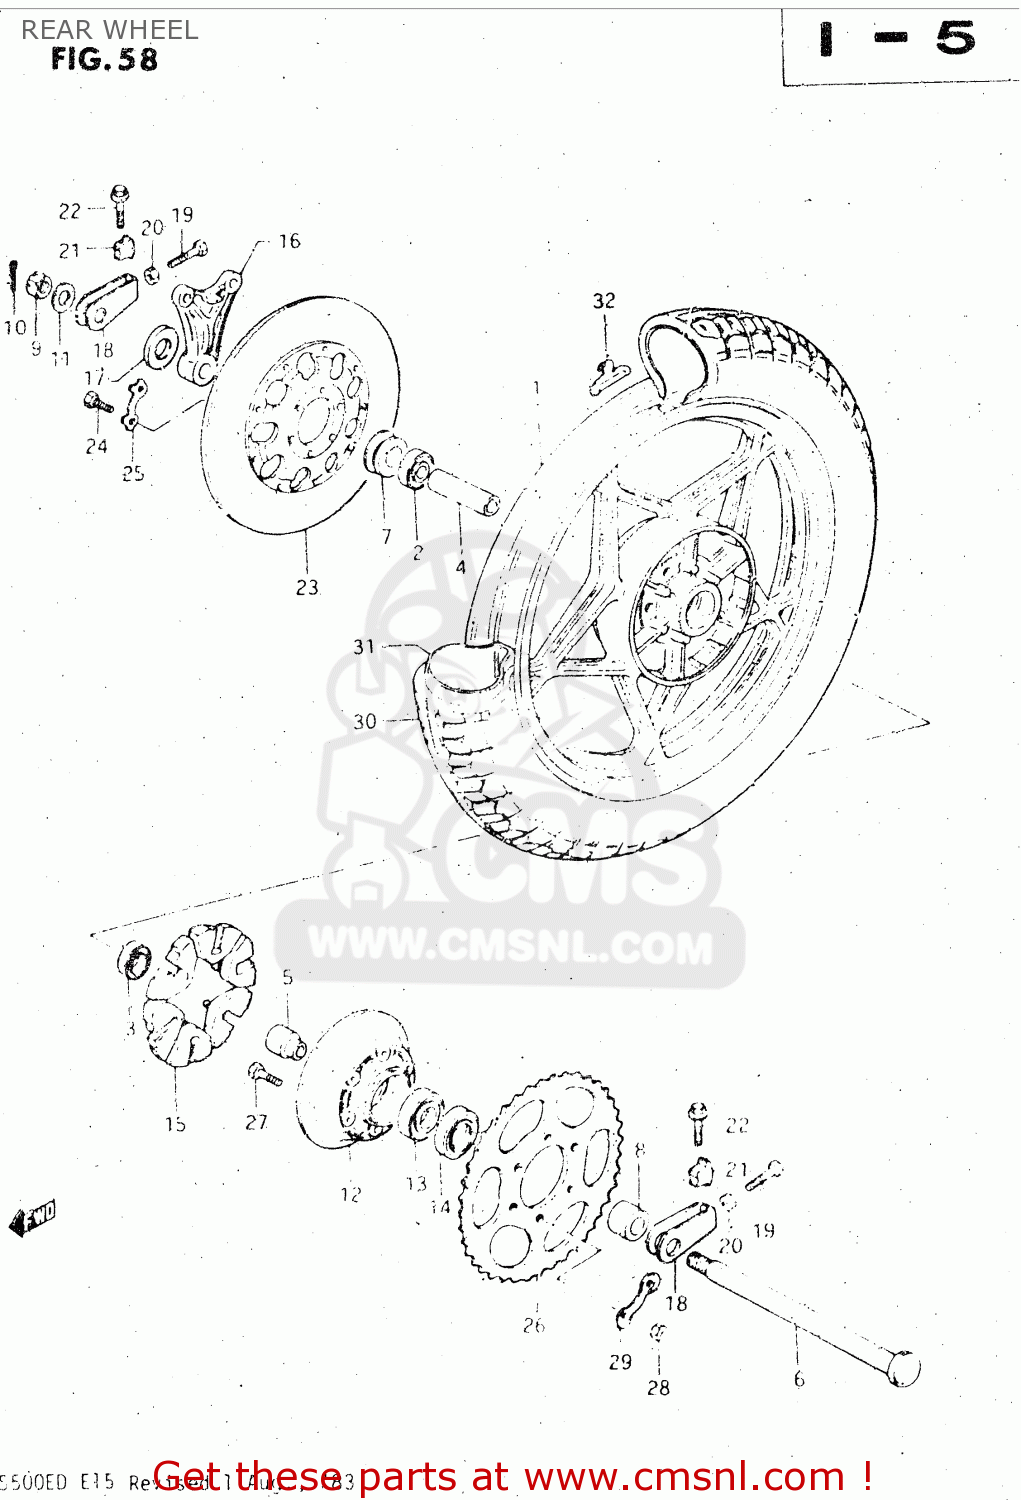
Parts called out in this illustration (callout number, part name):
1	CASTING WHEEL,REAR 2.15
2	BEARING
3	BEARING
4	SPACER,REAR HUB BEARING
5	RETAINER,REAR SPROCKET D
6	AXLE,REAR
7	SPACER,REAR AXLE
8	SPACER (17X33X21.1)
9	NUT
10	PIN,COTTER
11	WASHER (17X30X3.2)
12	DRUM,REAR SPROCKET MOUNT
13	BEARING
14	SEAL,OIL(33X62X7)
15	ABSORBER,REAR HUB SHOCK
16	BRACKET,RR,CALIPER
17	SPACER,REAR CARIPER BRACKET
18	ADJUSTER,CHAIN
19	BOLT 8X50
20	NUT
21	SUPPORTER,CHAIN ADJUST
22	BOLT
23	DISC,BRAKE
24	BOLT(8X30)
25	WASHER
26	SPROCKET,REAR
27	BOLT
28	NUT
29	WASHER
30	TIRE
31	TUBE ASSEMBLY,WHEEL,INNER
32	BALANCER,WHEEL
